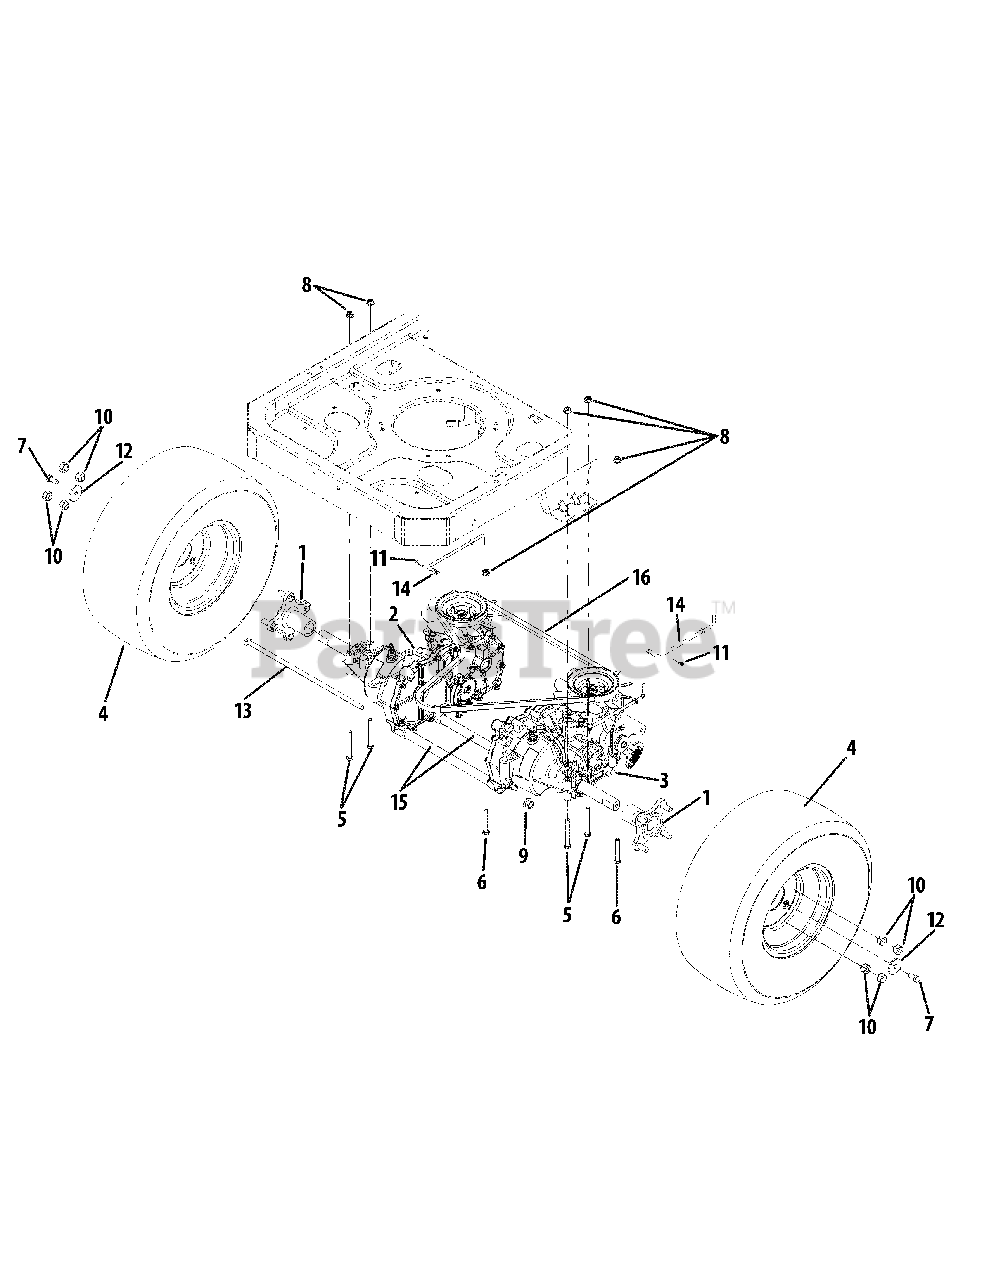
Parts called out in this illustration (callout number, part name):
1	Wheel Hub, 7/16-14 x 1.6
2	Transmission Assembly, LH
3	Transmission Assembly, RH
4	Wheel Assembly, 18 x 8.5-8 (42" Deck)
4	Wheel Assembly, 18 x 9.5-8 (50" Deck)
5	Hex Cap Screw, 5/16-18 x 2.75
6	Hex Cap Screw, 5/16-18 x 2.25
7	Hex Cap Screw, 3/8-16 x .75
8	Hex Flange Nut, 5/16-18
9	Hex Flange Nut, 7/16-20
10	Lug Nut, 7/16-14
11	Cotter Pin, 3/32 x .75
12	Flat Washer, .39 x 1.5 .134
13	Rod, .405 x 14.0
14	Bypass Rod
15	Tube, .45 x .69 x 10.2
16	V-Belt
